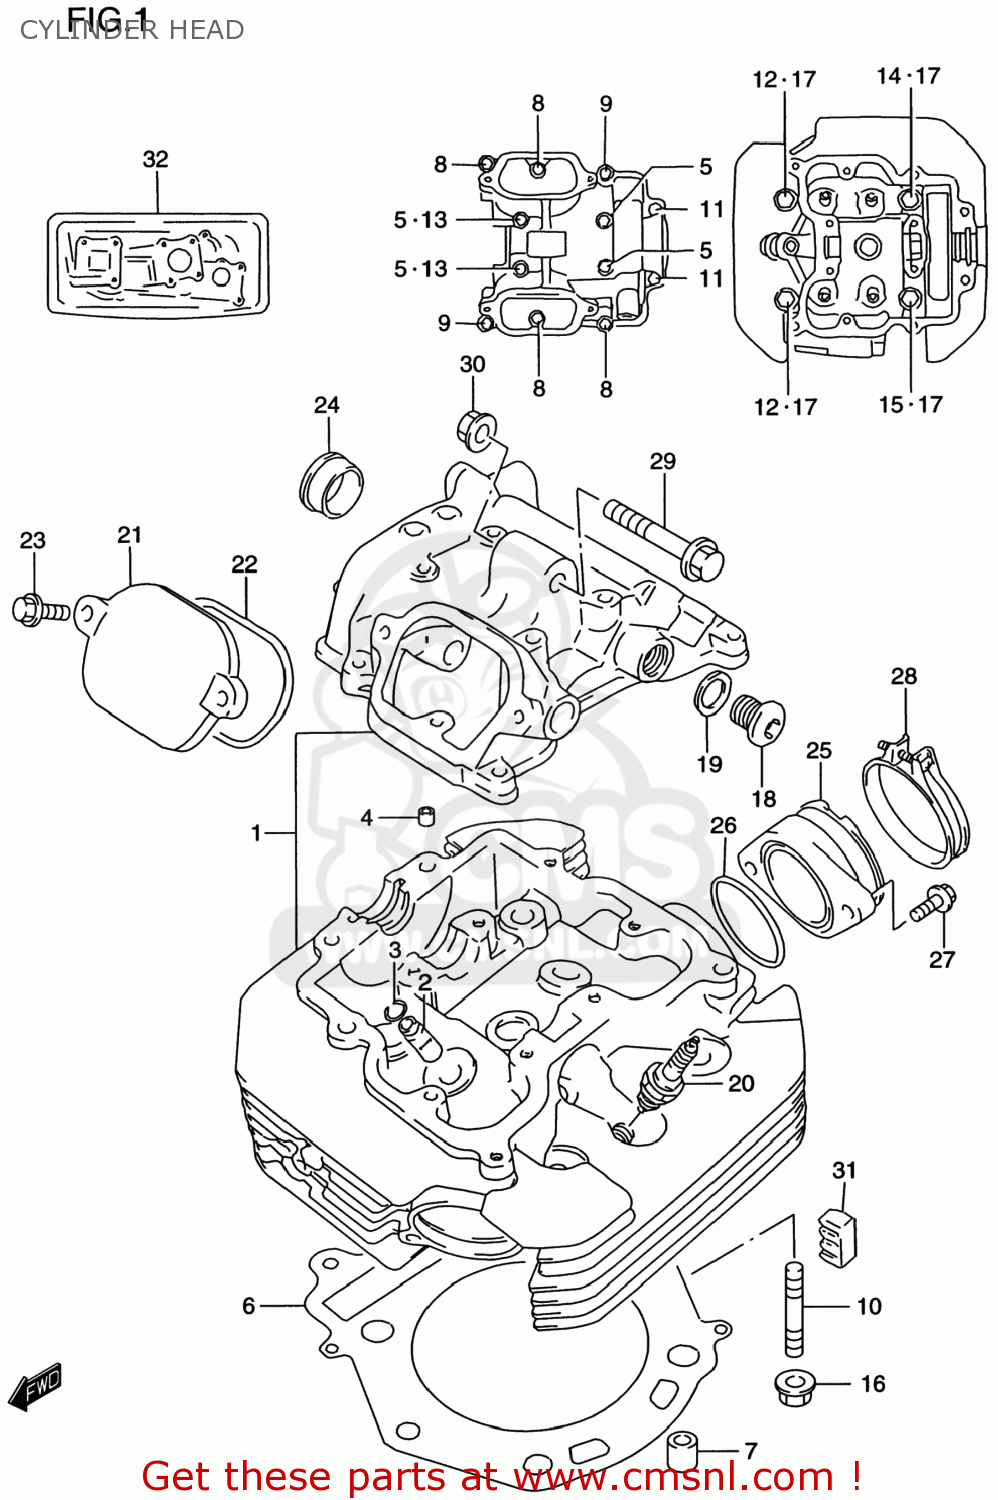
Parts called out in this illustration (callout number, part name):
1	HEAD ASSY,CYLINDER
2	GUIDE,VALVE
3	RING,SNAP
4	PIN(6.2X8X11)
5	BOLT(6X55)
6	GASKET,CYLINDER HEAD
7	PIN
8	BOLT
9	BOLT
10	BOLT,STUD
11	BOLT(6X115)
12	BOLT(10X180)
13	GASKET(5.8X13X1.2) (NAS)
14	BOLT(10X190)
15	BOLT(10X200)
16	NUT
17	GASKET(10.5X22X2) (NAS)
18	PLUG,14X12
19	GASKET(13.8X18.8X4.8) (NAS)
20	PLUG,SPARK(CR10E)
21	CAP,INSPECTION
22	O-RING,INSPECTION CAP
23	BOLT
24	PLUG,OD:30
25	PIPE,INTAKE
26	O RING(D:2.4,ID:45.7)
27	SCREW(6X16)
28	CLAMP
29	BOLT(8X53)
30	NUT
31	PAD,CYLINDER HEAD RUBBER
32	GASKET SET (NAS)
